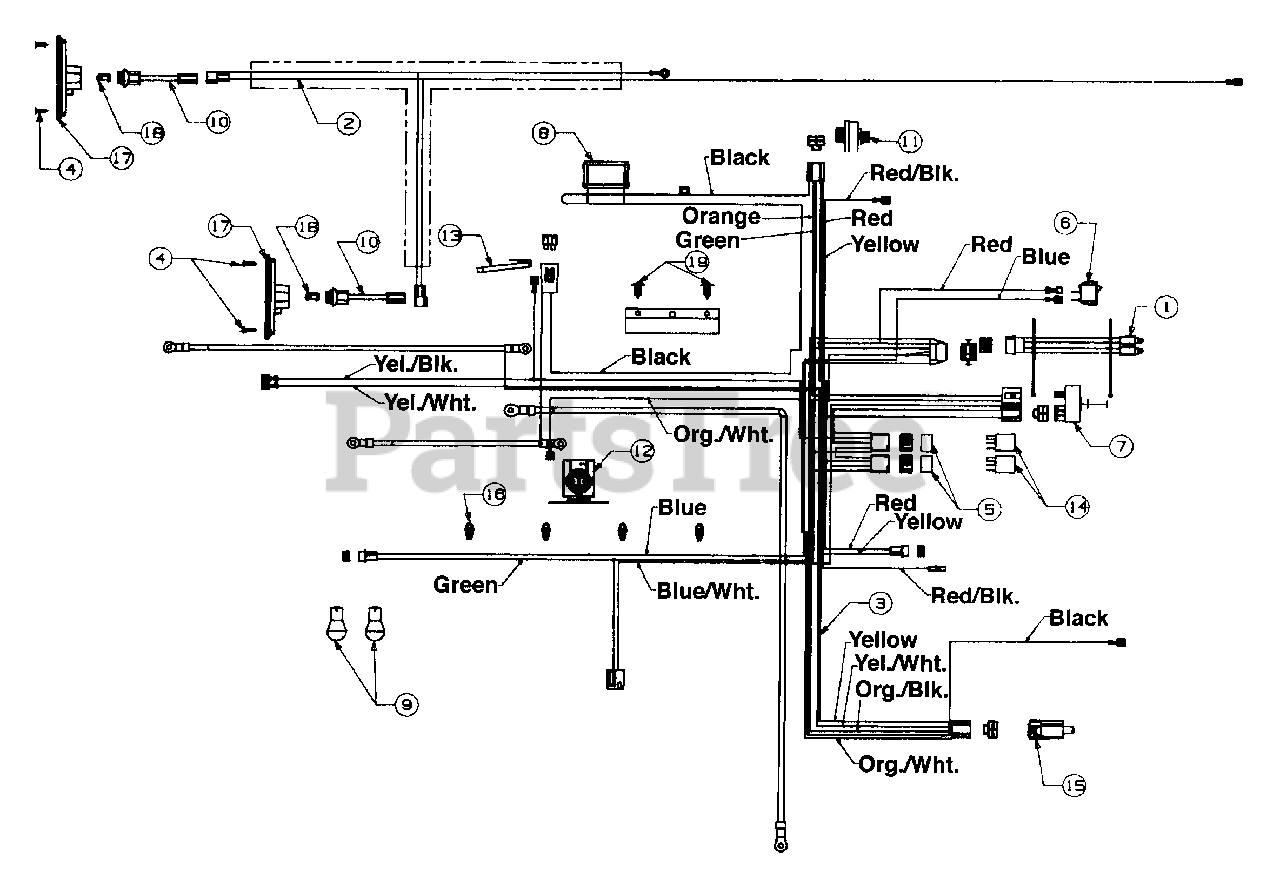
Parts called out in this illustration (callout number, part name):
1	Wire Harness (Monitor)
2	Wire Harness (Tail light)
3	Wire Harness
4	Truss Mach. Scr. #6-32 x .62" Lg.
5	Gasket - Relay
6	Light Switch
7	PTO Switch
8	Ammeter
9	Bulb (Headlight)
10	Tail light Harness
11	Ignition Switch
12	Solenoid
13	Safety Switch (Reverse)
14	Relay
15	Safety Switch
16	Wire Retainer Clip
17	Tail light
18	Bulb (Tail light)
